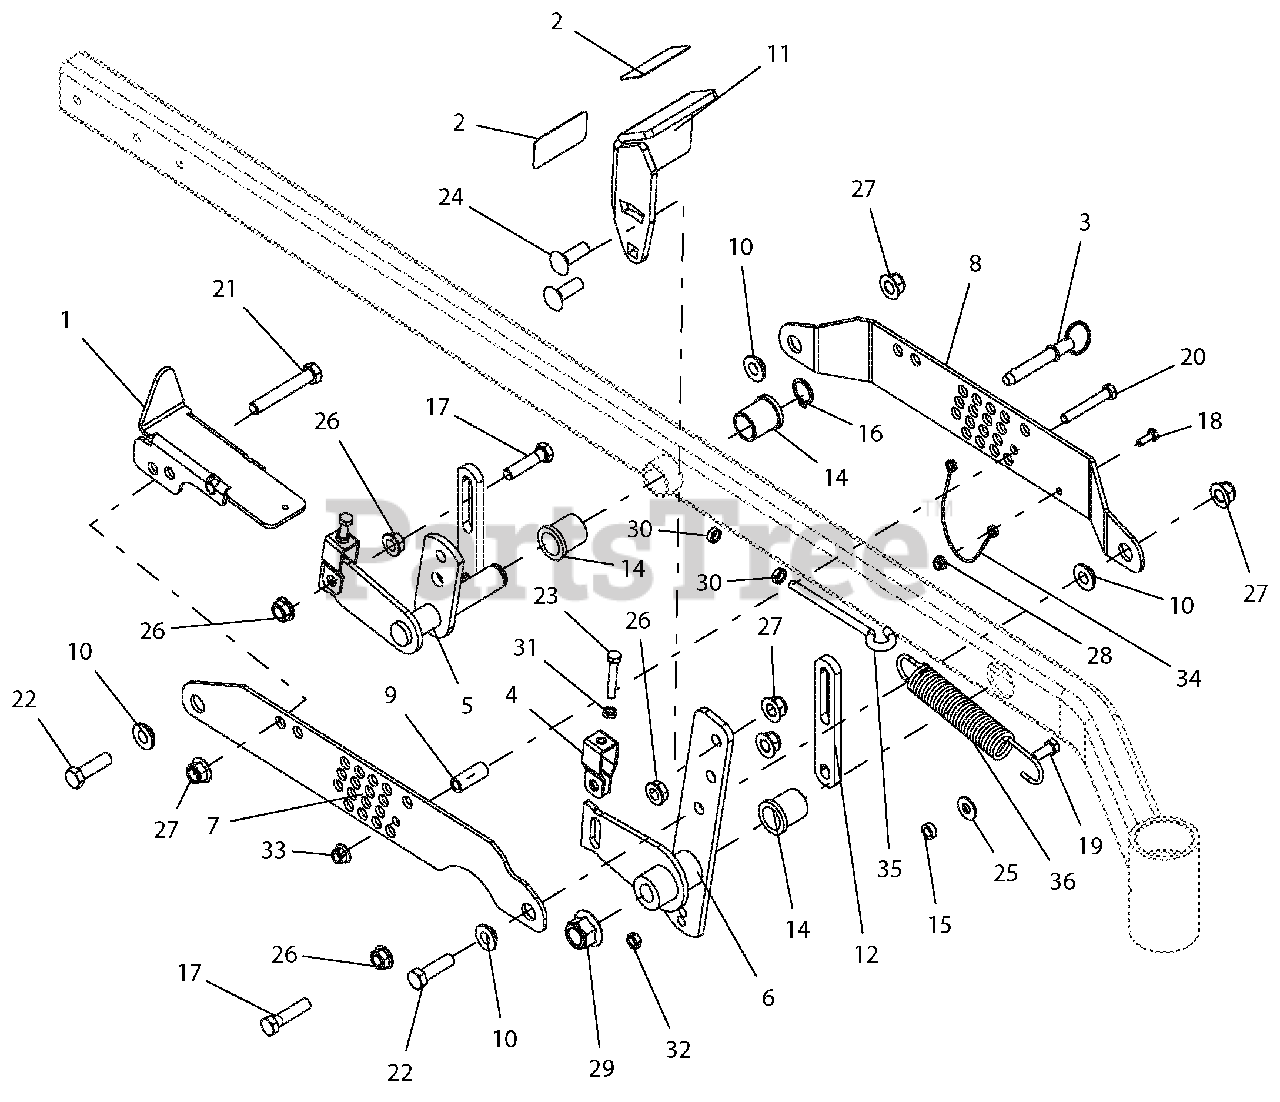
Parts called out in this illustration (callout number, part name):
1	WLDMT, MECHANICAL LOCK-UP-BLACK
2	GRIP, PEDAL 1.50 X 3.00
3	PIN, .50 X 2.00 USABLE LG BALL
4	BRKT, DECK LEVELING
5	WLDMT, REAR RH DECK LIFT
6	WLDMT, PT FRONT RH DECK LIFT ARM-BLACK
7	BRKT, RH OUTBOARD LIFT/CUT HEIGHT-BLACK
8	BRKT, RH INBOARD LIFT/CUT HEIGHT-BLACK
9	SPACER, .375 X .625 X 1.54
10	BSHG, FLANGE .515X.750X.31X1.12
11	PEDAL, ADJUSTABLE FOOT LIFT-BLACK
12	LINK, DECK LIFT - LONG
14	BSHG-FLG 1.00X1.25X1.5X1.5
15	BSHG, SLV .377X.624X.235
16	RG-RTNG-EXT 1.00X.078
17	BLT, HEX M12-1.75X50 CLS8.8 YZ
18	BLT-HEX .25-20X.75 GR5 YWZC
19	BLT-HEX .38-16X1.00 GR5 YWZC
20	BLT-HEX .38-16X2.50 GR5 YWZC
21	BLT-HEX .50-13X3.25 GR5 YWZC
22	BLT-HEX .50-13X1.75 GR5 YWZC
23	BLT-HEX .31-18X2.00 FTH GR5 YWZC
24	BLT-RDHDSQNK .50-13X1.50 G5 YWZC
25	WSHR-FL-STL.438X1.00X.083 YWZC
26	NUT, SPLK -FLG M12-1.75 YZ
27	NUT-LK-NYL-FLG .50-13 YWZC
28	NUT-LK-NYL-FLG .25-20 YWZC
29	NUT-LK-NYL-FLG .75-10 YWZC
30	NUT, JAM .375-16 YWZC
31	NUT, JAM .312-18 YWZC
32	@NUT-LK-CTR-JAM .375-16 YWZC
33	NUT-LK-NYL-FLG .38-16 YWZC
34	LANYARD, 12"
35	BOLT, EYE .38-16X6.00 .62 DIA
36	SPRG, TENSION .162 X 1.250 X 8.250
